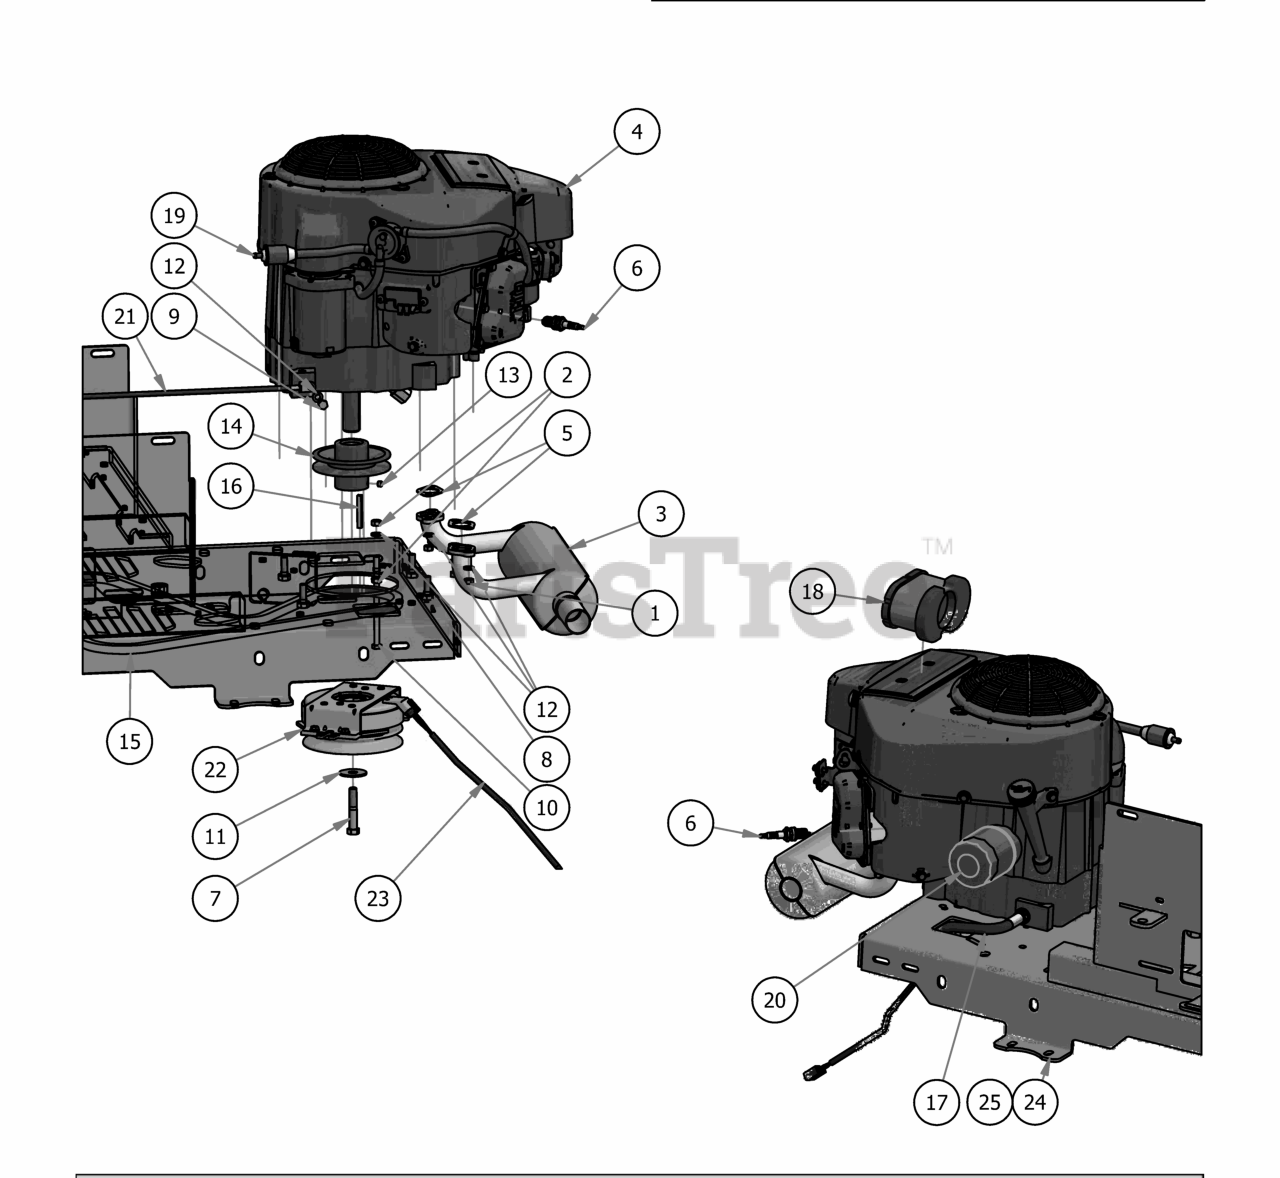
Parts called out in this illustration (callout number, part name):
1	M8-1.25 Zinc Nut
3	Kawasaki Muffler 1251
4	Kawasaki Engine-FR730V
5	Exhaust Gasket
6	Spark Plug - Kawasaki
7	7/16"-20 x 2.5" Hex Bolt Gr. 8
8	3/8 x 1 1/8 bolt
9	M8x1.20x20MM Hex head bolt
10	5/16-18 x 5-1/2 GR 5 Hex Bolt
11	1/2" Belleville Washer
12	5/16" Lock Washer
13	5/16 Set Screw
14	4 3/4 Motor Pulley
16	1/4 x 2 Square key Stock
17	Oil drain Hose
18	Kawasaki Air Filter
19	Universal Inline Fuel Filter
20	Kawasaki Oil Filter
21	24" Black Ground Cable
23	Clutch Pigtail
24	2017 MZ/ZT 54"-60" Frame
25	2017 MZ/ZT 42"-48" Frame
